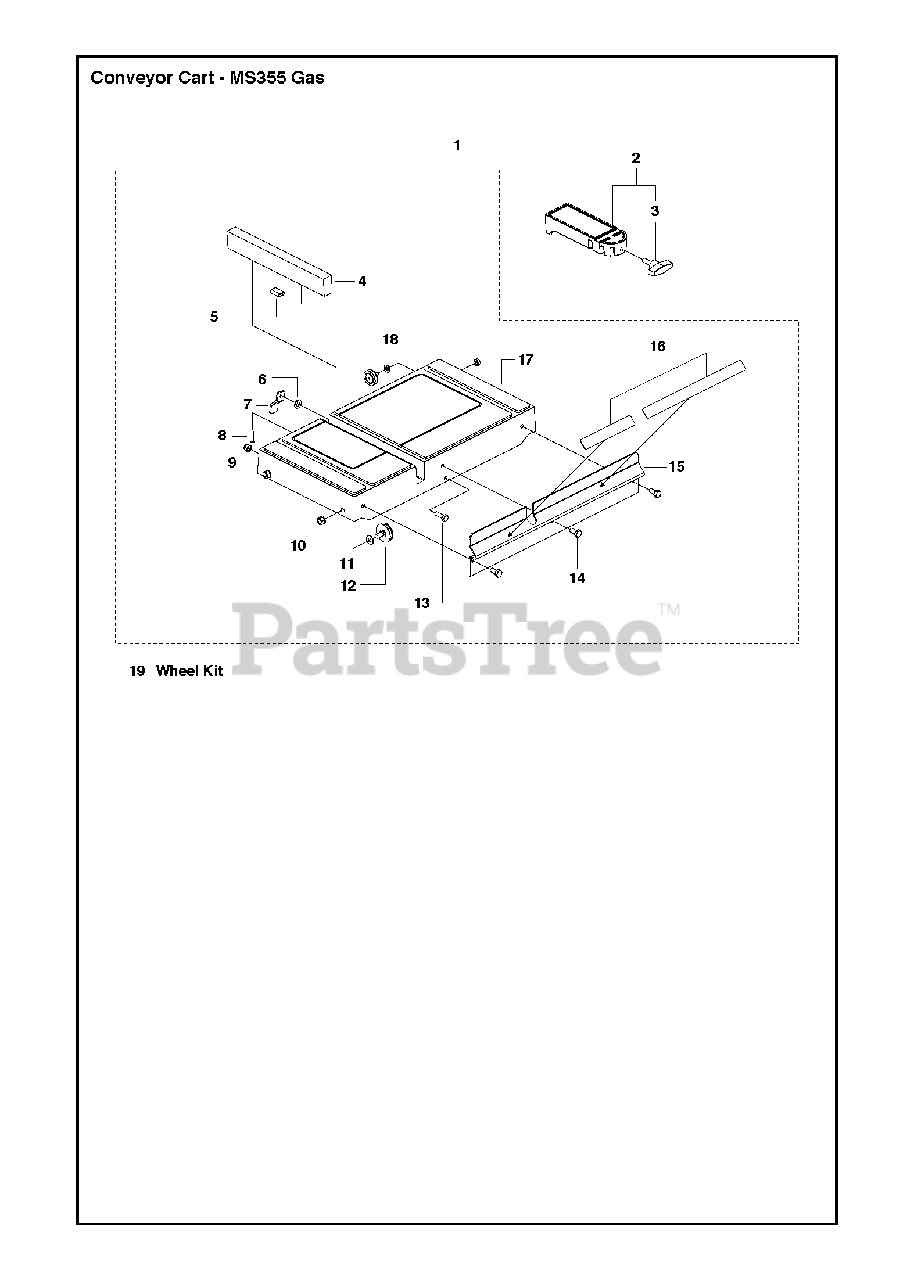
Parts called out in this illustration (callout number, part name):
9	NUT
11	WASHER
13	SCREW
18	FS700/2/900/2 WHEEL SUR/BEARIN
